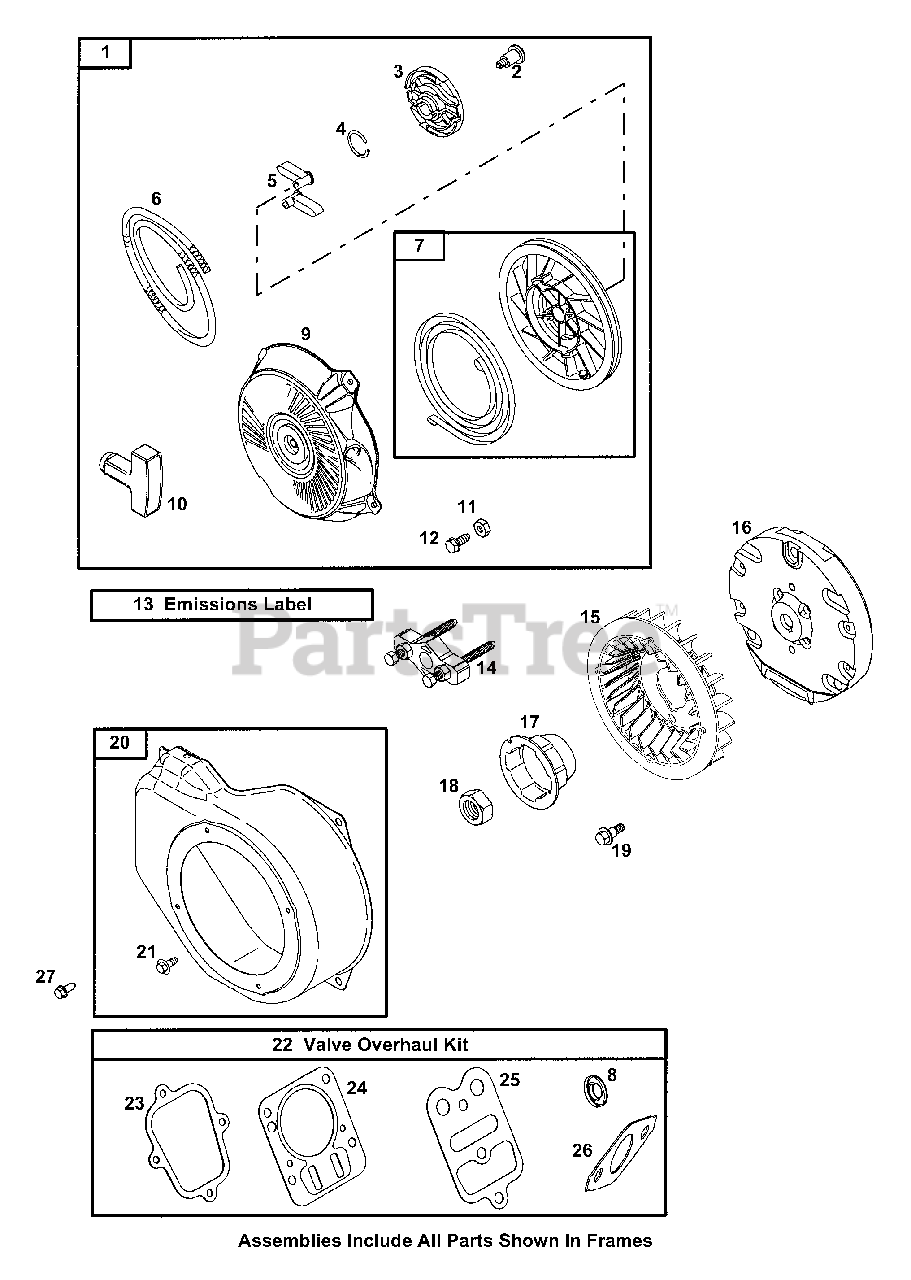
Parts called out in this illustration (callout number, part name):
1	Rewind Starter
2	Screw (Pawl Friction Plate)
3	Plate-Pawl Friction
4	Friction Spring
5	Pawl-Ratchet
6	Starter Rope
7	Pulley/Spring Assembly
8	Seal-Valve
9	Rewind Starter Housing
10	Starter Rope Grip
11	Nut (Rewind Starter)
12	Screw (Rewind Starter)
13	Emissions Label
14	Flywheel Puller
15	Fan-Flywheel
17	Flywheel Cup
18	Nut (Flywheel)
19	Screw (Flywheel)
20	Housing-Blower
21	Screw (Blower Housing)
22	Valve Overhaul Kit
23	Rocker Cover Gasket
24	Cylinder Head Gasket
25	Cylinder Head Plate Gasket
26	Intake Gasket
27	Screw (Blower Housing)
